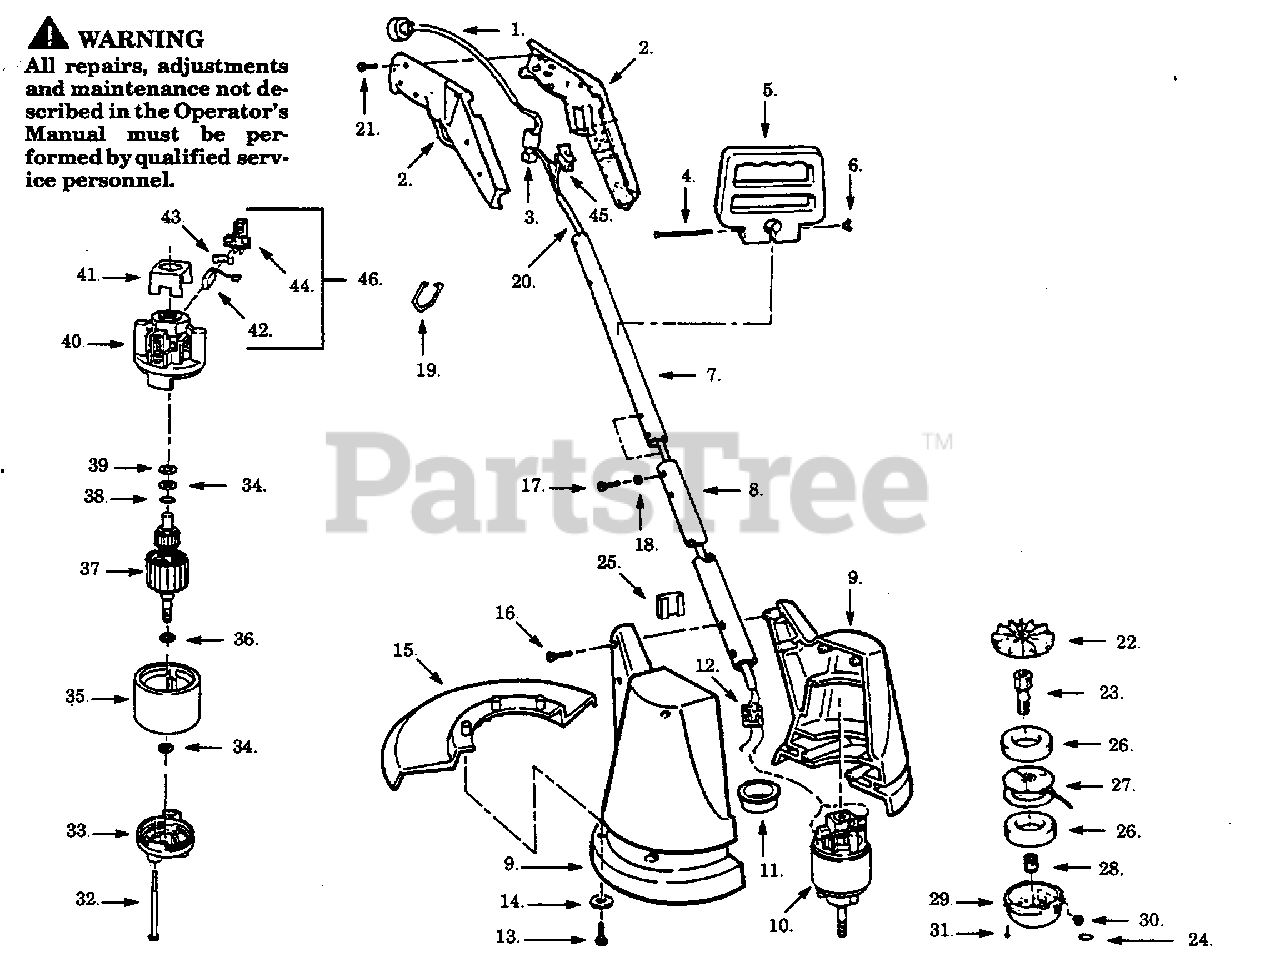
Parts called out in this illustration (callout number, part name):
1	Power Cord
2	R.H./L.H. Handle
3	Trigger Switch
5	Side Handle
6	Wing Nut
7	Upper Tube
8	Lower Tube
9	R.H./L.H. Housing
11	Air Baffle
12	P.C. Bridge Kit
15	Line Cutter Guard
18	Lockwasher
20	Harness Ass'y.
22	Rear Plate
23	Shaft Adaptor
24	Retaining Ring
25	Insulator
26	Foam Pad
27	Spool & Line
29	Hub Ass'y.
31	Cotter Pin
33	Endbell Ass'y. (Drive)
35	Field Ass'y.
36	Retaining Ring
37	Armature Ass'y.
38	Retaining Ring
40	Endbell Ass'y. (Brush)
41	Insulator
43	Brush Spring
44	Brush Holder
45	Power Switch
46	Brush Kit (Incl. 42,43,44)
